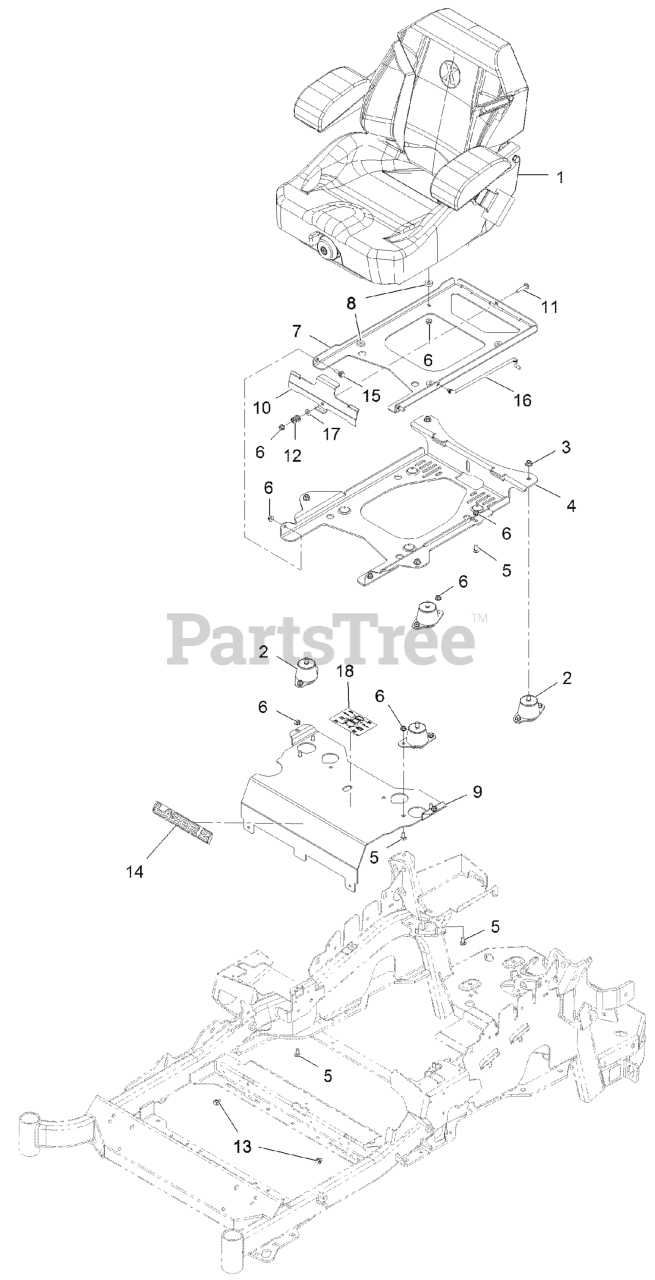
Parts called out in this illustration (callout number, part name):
1	KIT-SUSPENSION SEAT
2	ISOLATOR-SEAT
3	NUT-HF, NI
4	PLATE-TILT, SEAT SUPPORT
5	SCREW-CARR
6	NUT-HF, NI
7	PLATE-FRAME, SEAT
9	Panel-Front, Seat Mount
10	PLATE-LATCH, SEAT
11	BOLT-CARR
12	SPRING-COMPRESSION
14	DECAL, LAZER MODEL
15	SCREW-SHOULDER
16	ROD-PROP
17	WASHER-PLAIN
18	DECAL-SERVICE AID
